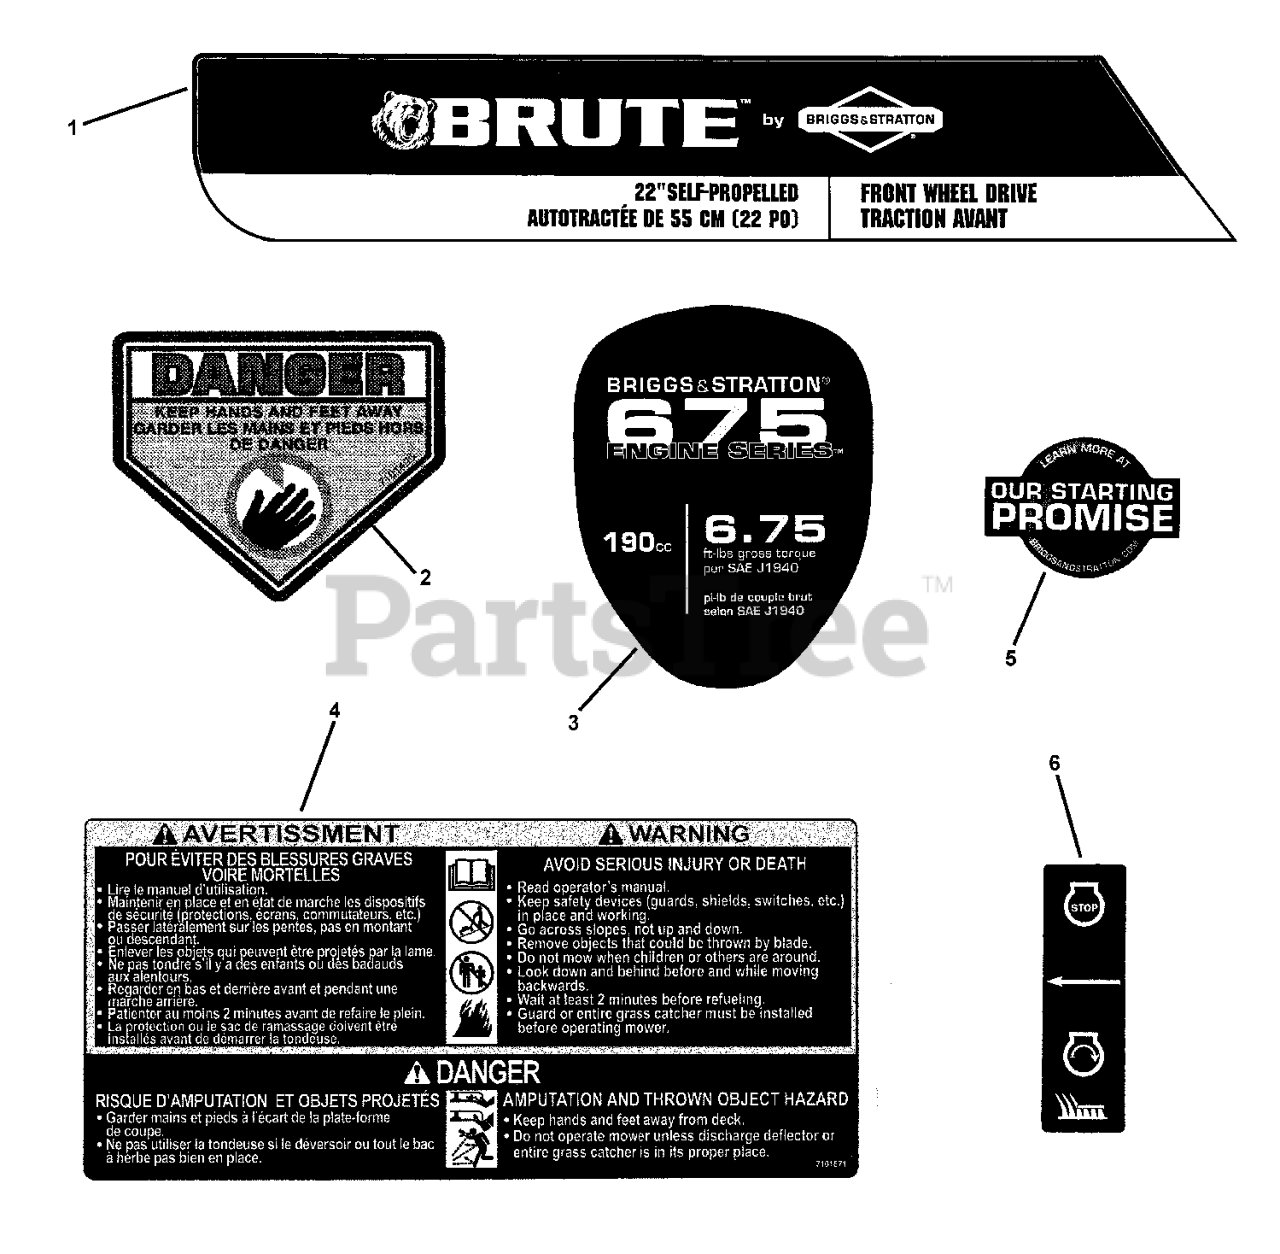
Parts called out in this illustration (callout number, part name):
1	DECAL, Deck Front 22" Propelled, FC
2	DECAL, CPSC, French/English
3	DECAL, Engine, TP, Brute 675 FC
4	DECAL, French/English, WB Safety
5	DECAL, Starting Promise
6	DECAL, OPC Bail International Symbol
